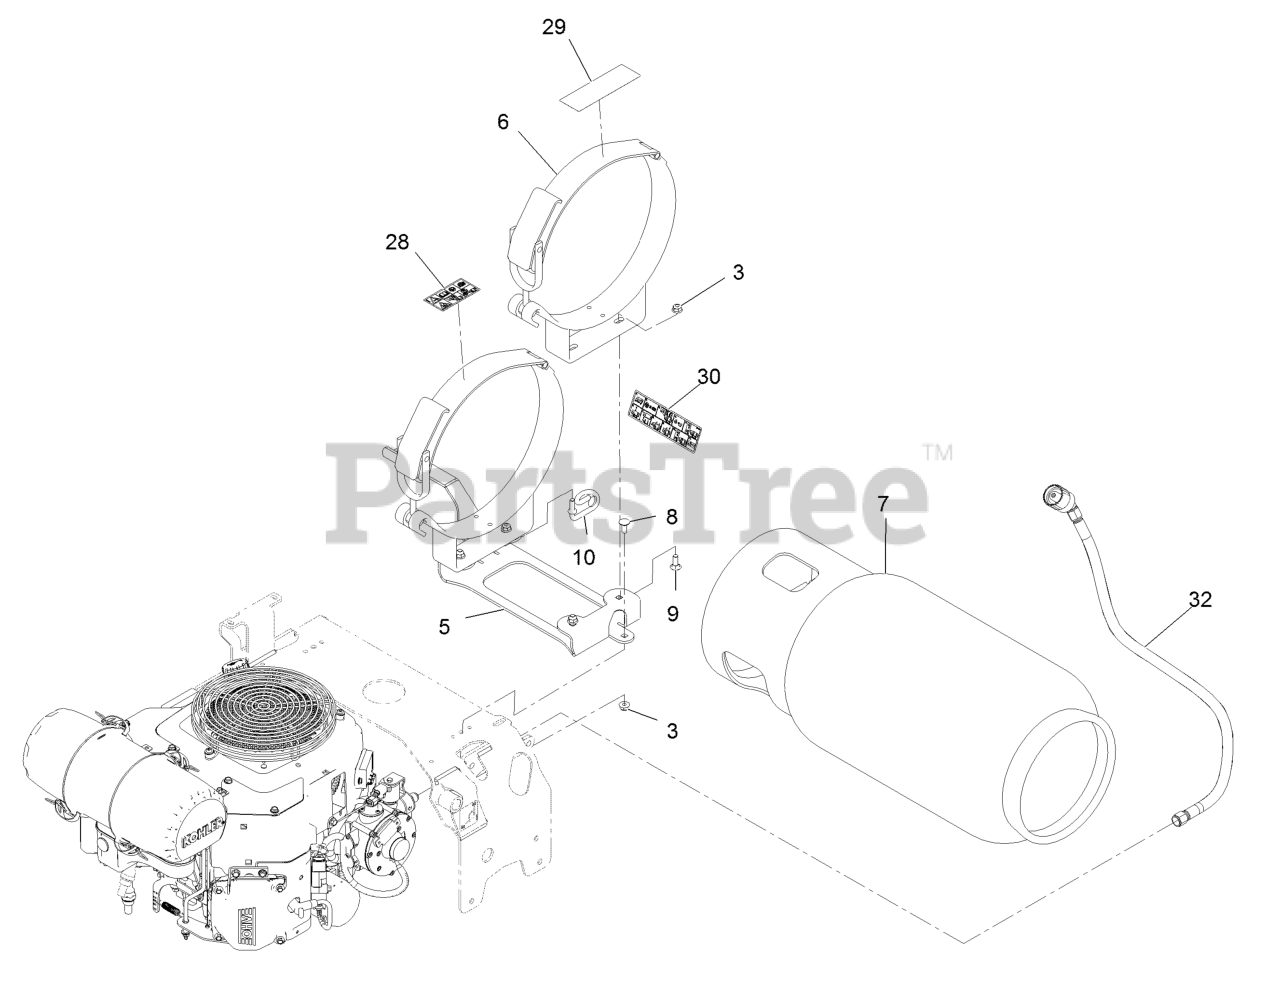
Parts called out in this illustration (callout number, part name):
3	NUT-HF, NI
5	WELD, TANK MOUNT
6	BRACKETS, LPG TANK - HORI
7	TANK, LP - 33.5 LB.HORIZO
8	SCREW-CARR
9	SCREW-CARR
10	RETAINER, LP HOSE
28	Decal-LPG Warning
29	Decal-LPG Horiz Tank Spec
30	Decal-LPG Fuel Tank Replacement
32	ASM, LPG HOSE W/CONNECTOR
